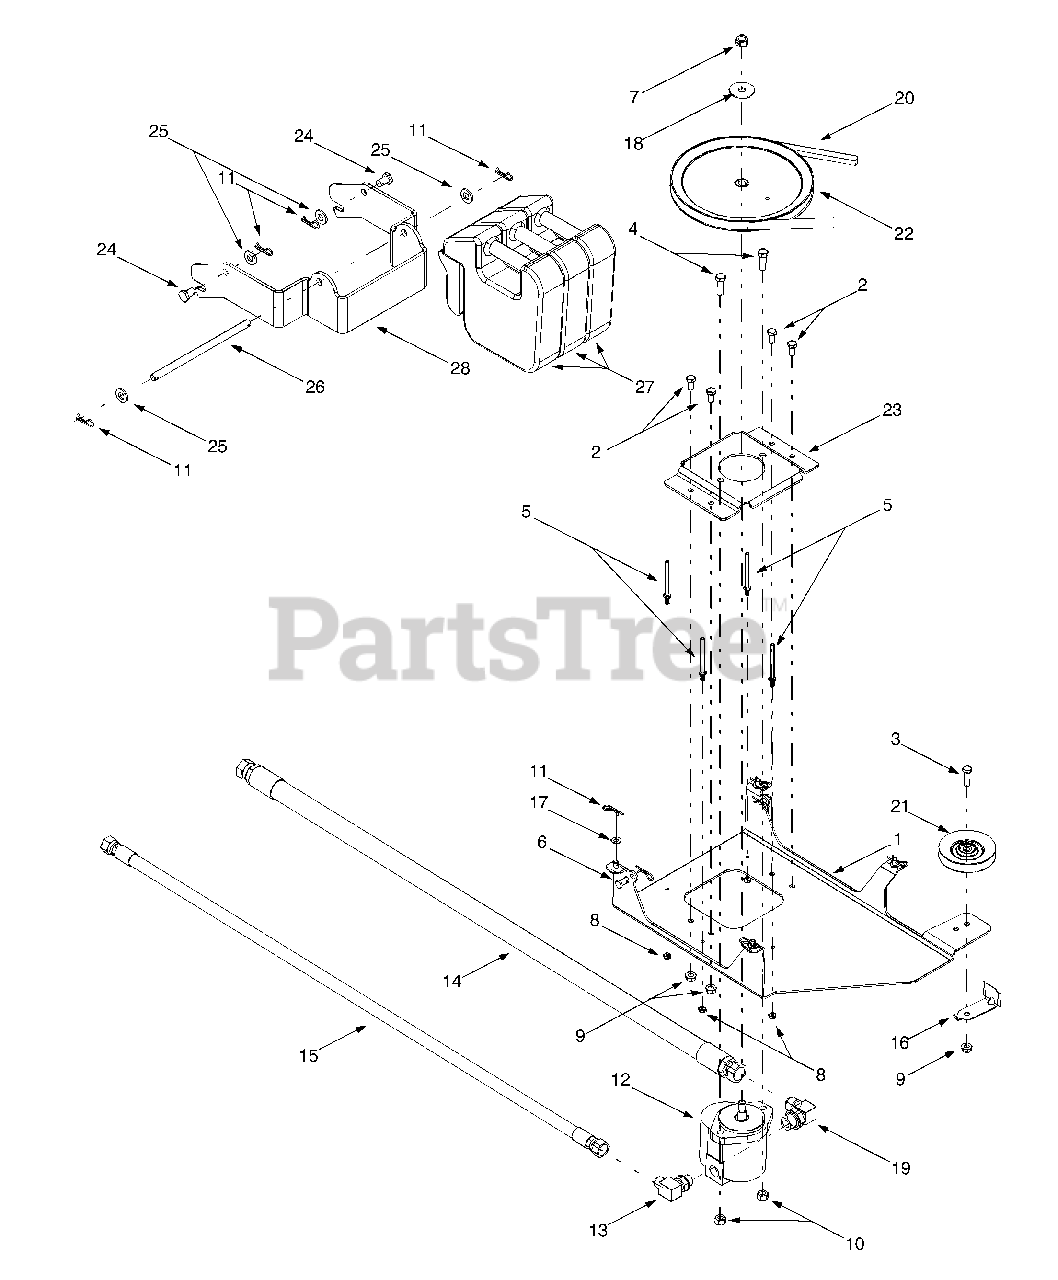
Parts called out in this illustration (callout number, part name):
3	Hex Cap Screw, 3/8-16 x 1.25
4	Hex Cap Screw, 7/16-20 x 1.25
5	Belt Keeper Pin
6	Clevis Pin, 3/8 x .75
7	Hex Lock Nut, 1/2-20
8	Hex Lock Nut, 1/4-20
9	Hex Lock Nut, 3/8-16
10	Hex Lock Nut, 7/16-20
11	Click Pin, .092 x 1.64
12	Eaton Hydraulic Pump
13	90° Hydraulic Adapter, 7/8
14	Hydraulic Hose, 1.0625-12 x 54
15	Hydraulic Hose, .875-14 x 49
16	Belt Guard
17	Flat Washer, .344 x .688 x .065
18	Flat Washer, .531 x 1.75 x .090
19	90° Hydraulic Adapter, 1-1/16
20	V-belt
21	Idler Pulley, 5/8 x 4.0
22	Drive Pulley, 10.0
25	Flat Washer, .531 x 1.062 x .134
26	Weight Guard Rod
27	45 lb. Suitcase Weight
